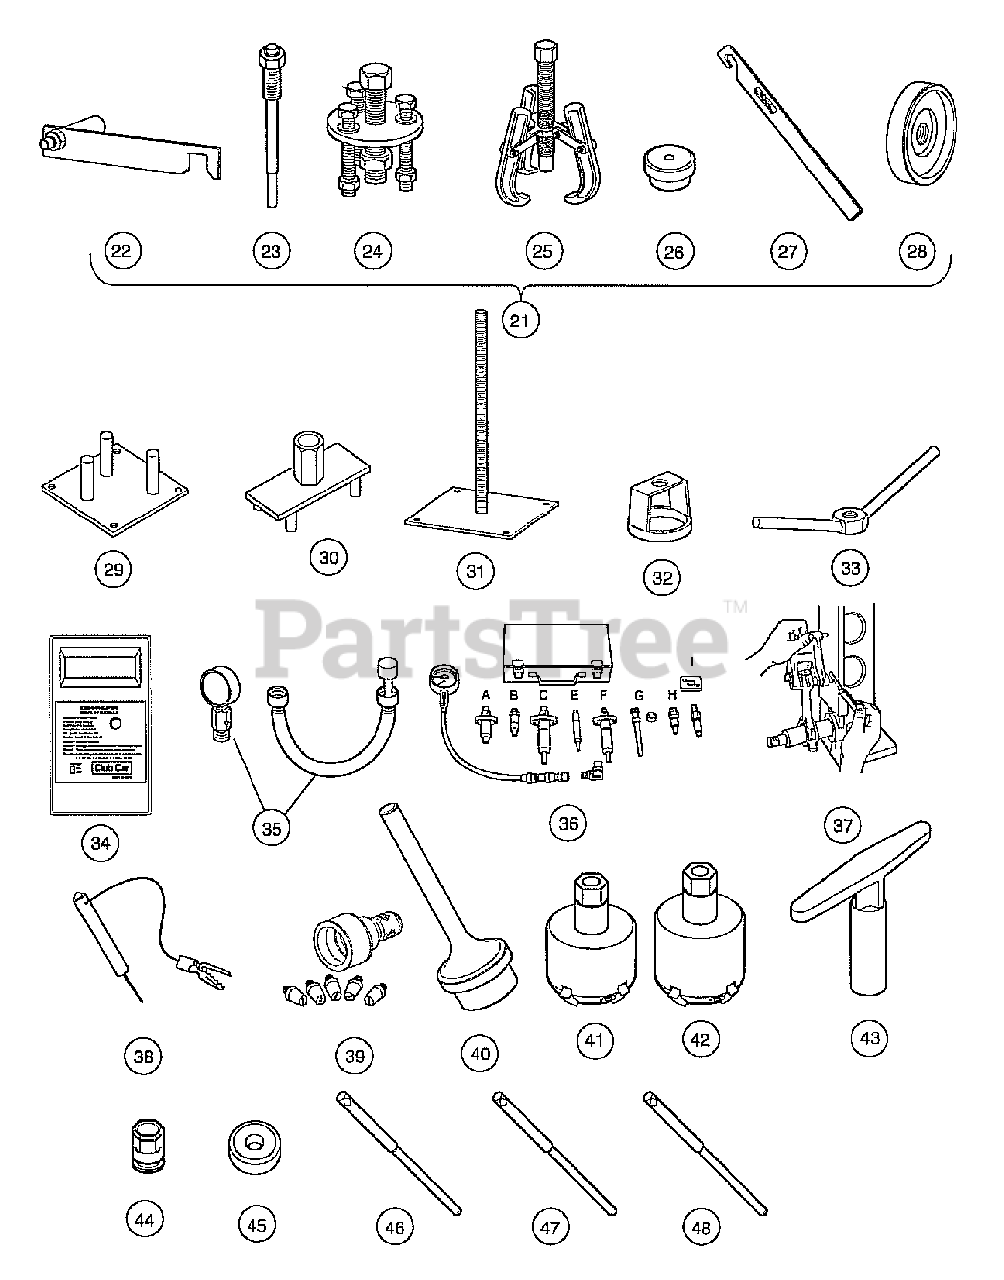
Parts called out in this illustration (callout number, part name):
21	Clutch Tool Kit
22	Clutch Alignment Tool
23	Drive Clutch Puller
24	Drive Clutch Hub Puller
25	Driven Clutch Cam Puller
26	Driven Clutch Puller Plug
27	Drive Clutch Holder Tool Assembly
28	Press Weldment
29	Clutch, Drive, Fixed Sheave Tool
30	Clutch, Drive, Spider Removal Tool
31	Clutch, Driven, Spring Compression Base
32	Clutch, Driven, Spring Compression Collar
33	Clutch, Driven, Spring Compression Nut
34	Communication Display Module
35	Compression Gauge and Adapter
36	Compression Tester
37	Connecting Rod Alignment Tool
38	Continuity Tester
39	Crank Sleeve Setter
40	Crankshaft Bearing Replacement Tool
41	Cutter, Valve Seat, #122
42	Cutter, Valve Seat #115
43	Wrench, T, #505
44	Adapter, T-Wrench
45	Cutter, Valve Seat, 60 Degree (requires item 59)
46	Pilot, 6.6 MM
47	Pilot, 6.62 MM
48	Pilot, 6.65 MM
